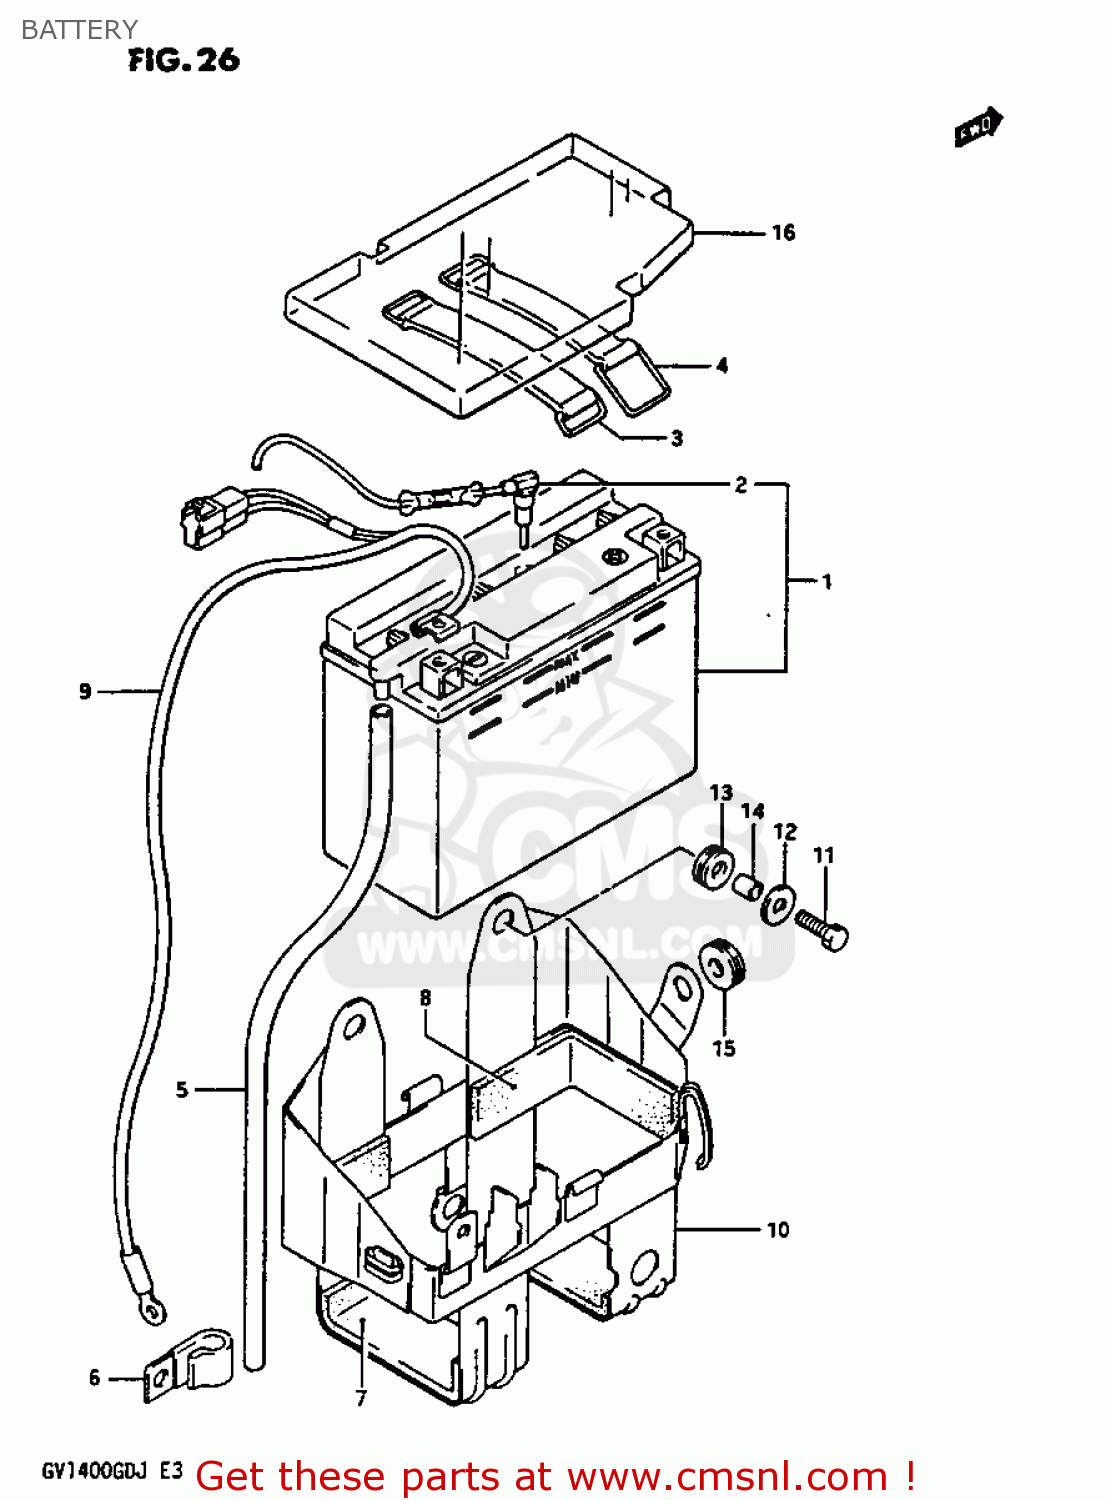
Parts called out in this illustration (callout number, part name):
1	BATTERY ASSEMBLY (12V)
2	SENSOR,BATTERY LEVEL
3	BAND
4	BAND
5	HOSE,BATTERY EXHAUST(L:780)
6	CLAMP
7	PROTECTOR(170X95X3.0)
8	PROTECTOR(170X95X3.0)
9	WIRE,BATTERY MINUS
10	HOLDER,BATTERY
11	BOLT,M6X1X20
12	WASHER(6.5X20X1.6)
13	CUSHION
14	SPACER(6.2X9X7.5)
15	CUSHION
16	COVER,BATTERY
